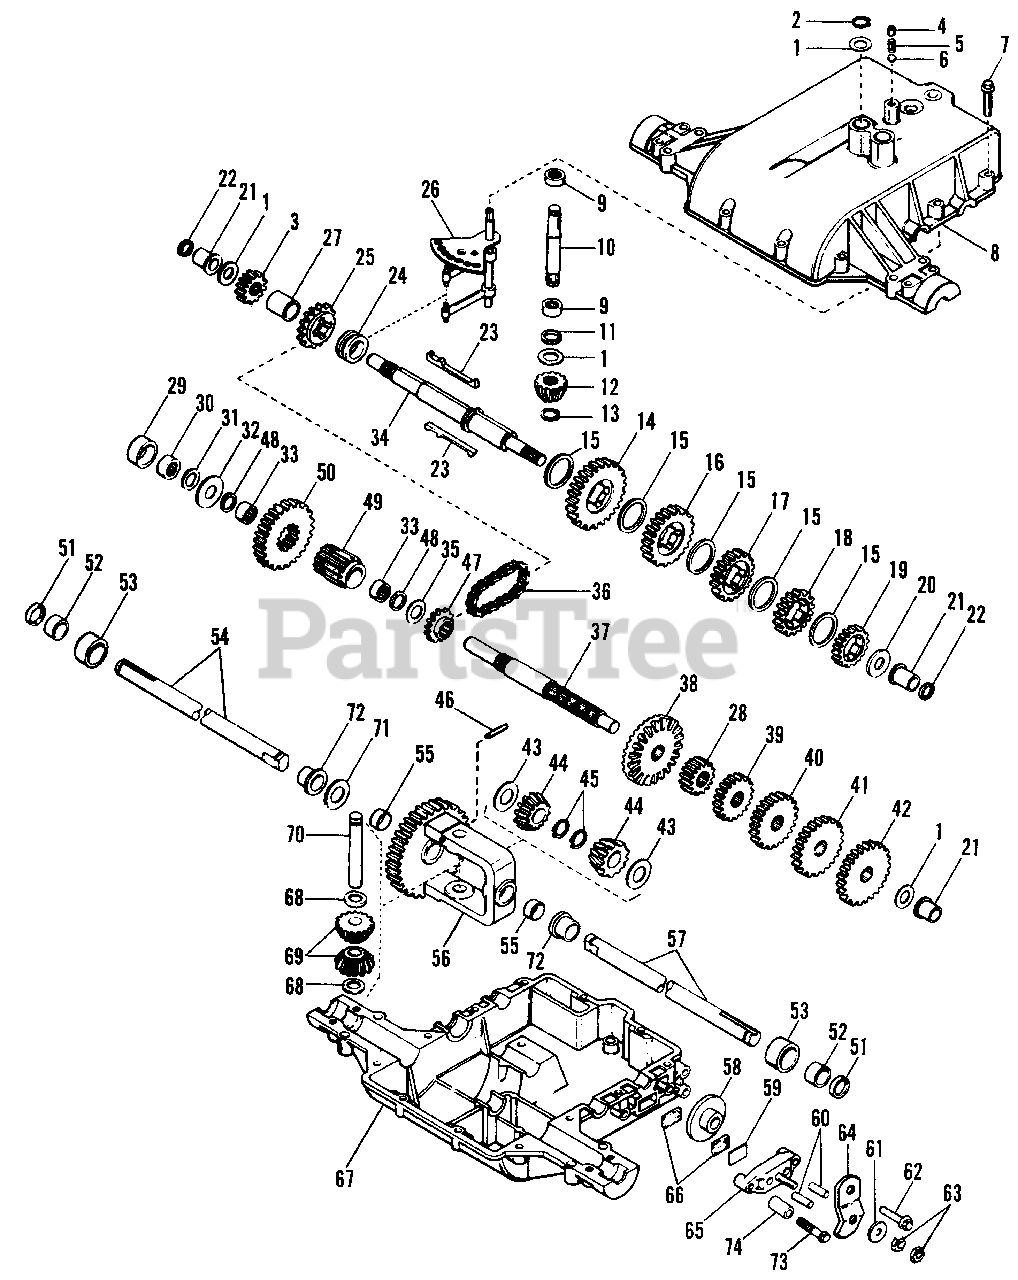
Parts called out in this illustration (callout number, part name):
1	WASHER, Thrust
2	RING, Retaining
3	GEAR, Spur (15 teeth)
4	SCREW, Set, 3/8-16 x 3/8
6	BALL, Steel
7	SCREW, Hex Hd., Thd. Forming, 1/4-20 x 1-1/4
8	COVER, Transaxle
9	BEARING, Needle
10	SHAFT, Input
11	RING, Square Cut
12	BEVEL PINION, Input
13	RING, Retaining
14	GEAR, Spur (37 teeth)
15	WASHER, Thrust
16	GEAR, Spur (30 teeth)
17	GEAR, Spur (25 teeth)
18	GEAR, Spur (22 teeth)
19	GEAR, Spur (20 teeth)
20	WASHER, Thrust
21	BUSHING, Flanged
22	RING, Square Cut
24	COLLAR, Shift
25	SPROCKET (18 teeth)
26	ROD & FORK ASSY., Shift
28	GEAR, Spur (12 teeth)
30	BEARING, Needle
31	RING, Square Cut
32	WASHER, Flat
33	BEARING, Needle
34	SHAFT, Brake
35	WASHER, Flat
36	CHAIN, Roller (No. 41 Chain, 24 links)
37	SHAFT, Counter
38	GEAR, Bevel (42 teeth)
39	GEAR, Spur (20 teeth)
40	GEAR, Spur (25 teeth)
41	GEAR, Spur (28 teeth)
42	GEAR, Spur (30 teeth)
43	WASHER, Thrust
44	GEAR, Bevel
45	RING, Retaining
46	PIN, Roll
47	SPROCKET (9 teeth)
48	RING, Square Cut
49	PINION, Output
50	GEAR, Output
51	SEAL, Oil
52	BEARING, Needle
54	AXLE (12-1/8" long)
56	GEAR ASSY., Differential (Incl. 2 of No. 60)
57	AXLE (15-1/8" long)
58	BRAKE, Disk
59	PLATE, Brake Pad
60	PIN, Dowel
61	WASHER, Flat
62	SCREW, Hex Hd., Thd. Forming, 1/4-20 x 1-1/4
63	LOCKNUT, 5/16-24
64	LEVER, Brake
65	HOLDER, Brake Pad
66	PAD, Brake
67	CASE, Transaxle
68	WASHER, Thrust
69	PINION, Bevel
70	PIN, Drive
72	BUSHING, Flanged
73	SCREW, Hex Hd., Thd. Forming, 1/4-20 x 2-1/4
